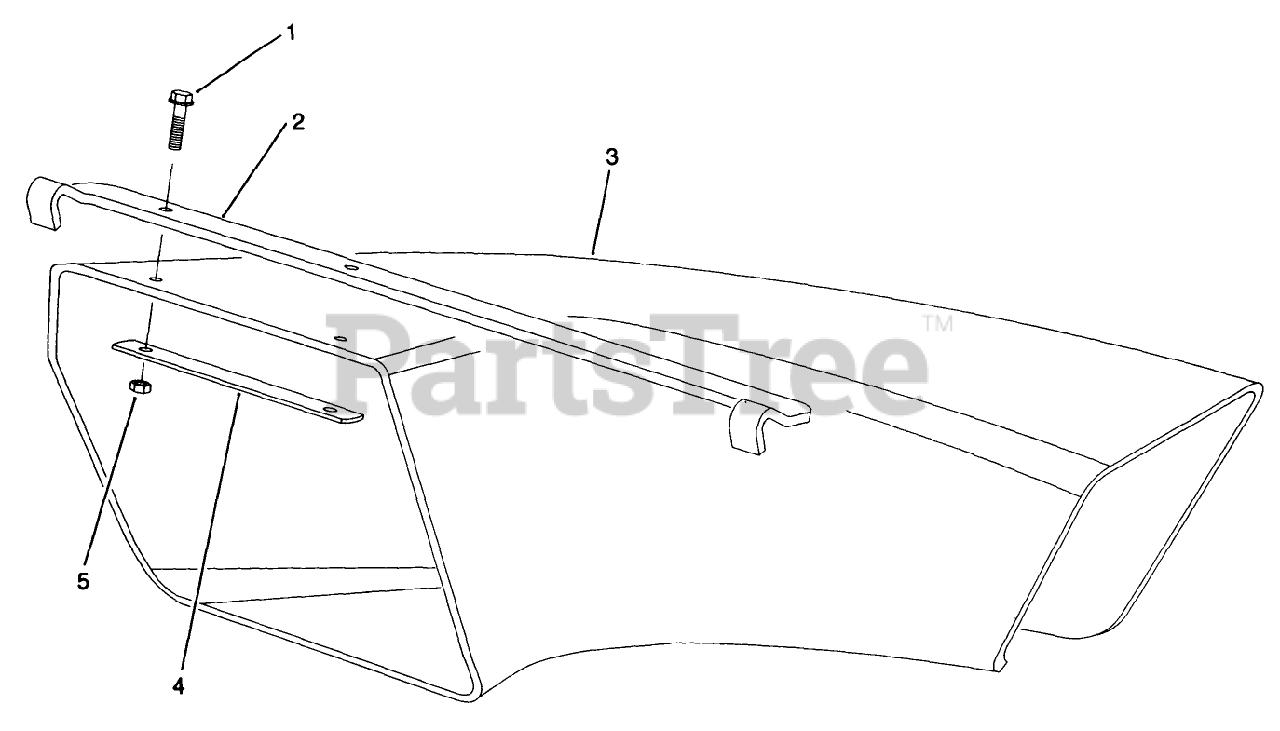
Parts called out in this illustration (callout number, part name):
1	SCREW-HWH
2	CHUTE HANGER BRACKET*
4	NUT-LOCK, NI
